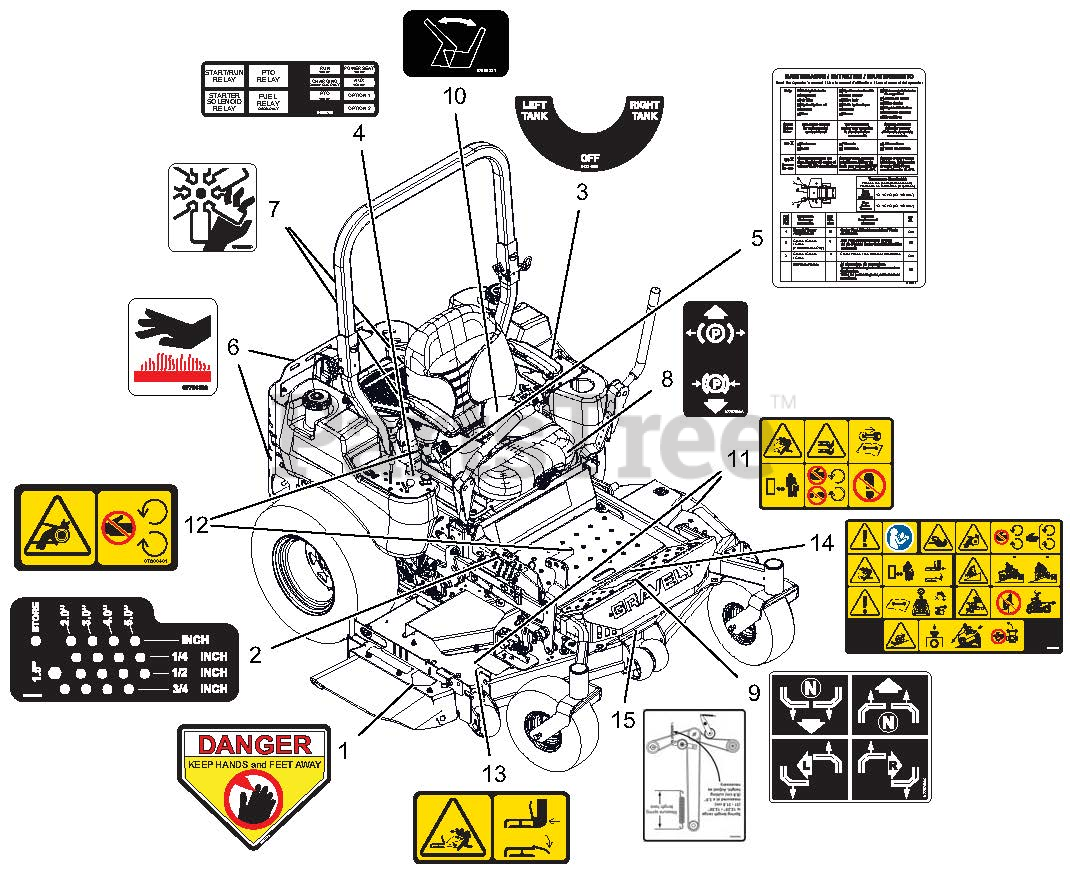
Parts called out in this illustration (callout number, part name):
1	DECAL, DANGER
2	DECAL, HEIGHT OF CUT
3	DECAL, FUEL VALVE
4	DECAL, FUSE BOX
5	DECAL, MAINTENANCE
6	DECAL HOT SURFACE
7	DECAL, DANGER - FAN
8	DECAL, PARKING BRAKE LEVER
9	DECAL, INSTRUCTIONAL - STEERING
10	DECAL, SEAT RELEASE
11	DECAL, SAFETY - MOWER DECK
12	DECAL, SAFETY - GUARDING
13	DECAL, SAFETY - DECK GUARDING
14	DECAL, MAIN SAFETY, COMMERCIAL
15	DECAL, BELT DIAGRAM
